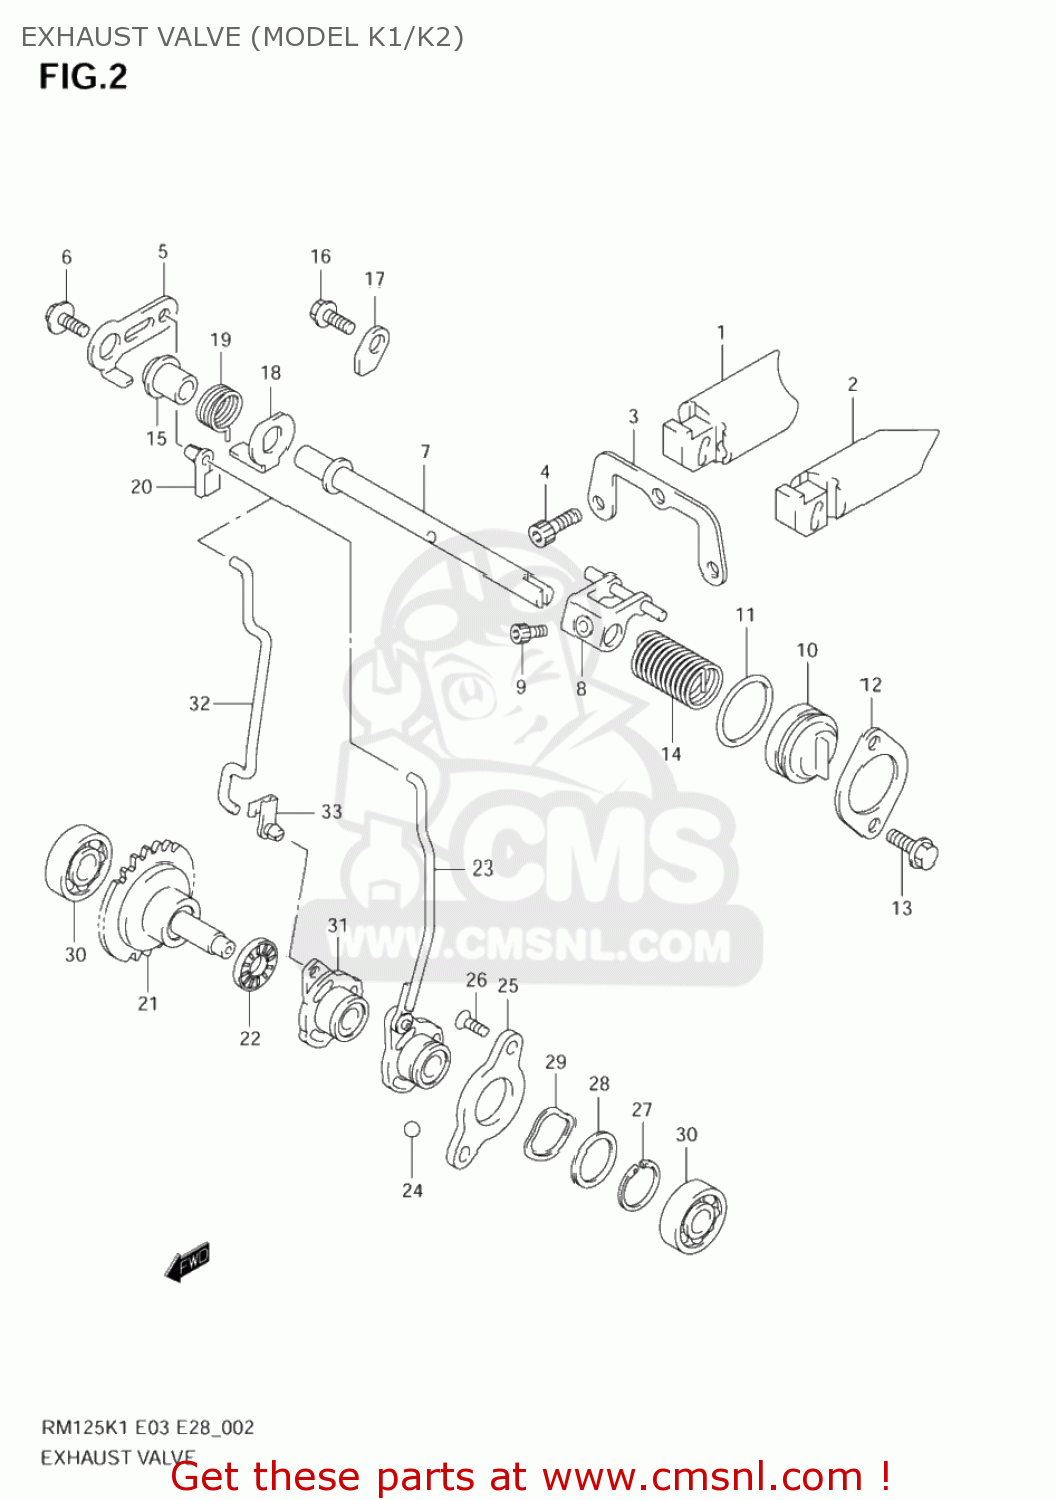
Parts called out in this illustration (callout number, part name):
1	VALVE,EXHAUST,R
2	VALVE,EXHAUST,L
3	PLATE,EXHAUST VALVE
4	BOLT
5	LEVER,EXHAUST VALVE NO.1
6	BOLT(5X12)
7	SHAFT,EXHAUST VALVE
8	ARM,EXHAUST VALVE SHAFT
9	BOLT(4X8)
10	CAP,EXHAUST VALVE
11	O RING(D:1.9,ID:22.6)
12	RETAINER,EXHAUST VALVE
13	BOLT
14	SPRING,EXHAUST VALVE
15	SPACER,EXHAUST VALVE
16	BOLT
17	RETAINER
18	LEVER,EXHAUST VALVE NO.2
19	SPRING
20	BUSH,EXHAUST VALVE ROD NO.1
21	GOVERNOR ASSY,EXHAUST VALVE
22	BEARING(10X22X2.8)
23	ACTUATOR,EXHAUST VALVE
24	BALL
25	STARTER,EXHAUST VALVE ACTUATOR
26	SCREW(5X10)
27	CIRCLIP
28	SHIM(19.1X25X0.3)
29	WASHER
30	BEARING(8X22X7)
31	ACTUATOR,EXHAUST VALVE
32	ROD,EXHAUST VALVE
33	BUSH,EXHAUST VALVE ROD NO.1
